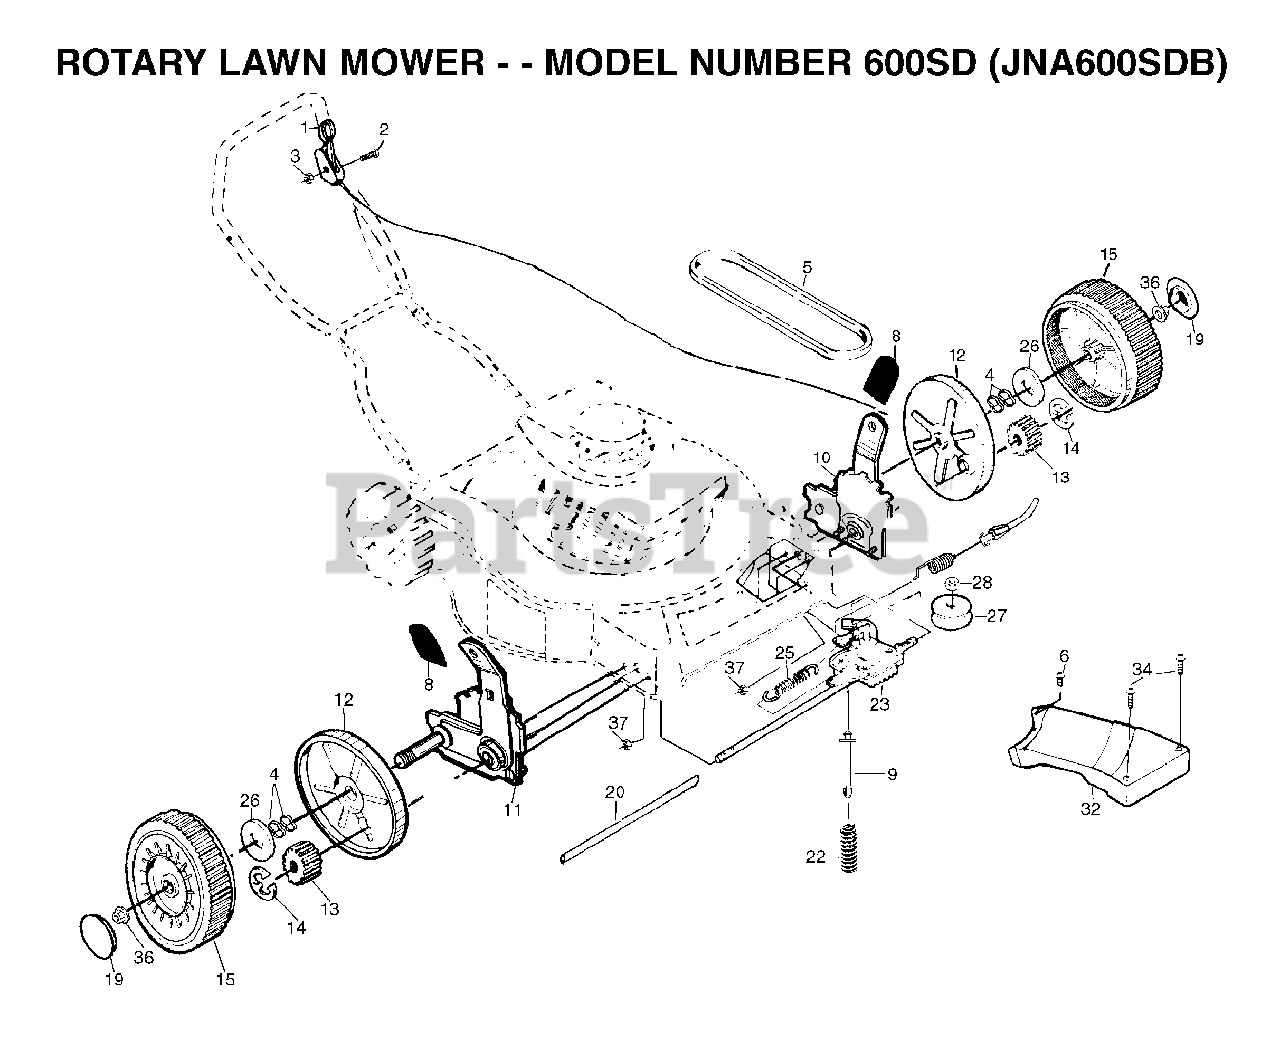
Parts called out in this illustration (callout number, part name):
1	CONTROL
4	WAVE WASHER
5	BELT THERM .32
6	TAPPING SCREW
8	SELECTOR KNOB
9	SPRING RETAINER
12	DUST COVER, WHEEL
13	PINION GEAR
14	E-RING 7/16 RE
15	WHEEL.8X2.RADIAL.GRAY
20	DRV SHAFT TUBE PM
22	SPRING.EXTENSION
23	GEAR CASE ASMBLY
26	WASHER FLUT
27	PULLEY
28	FLANGED LOCKNUT 3/8-16 ZINC
36	HEX FLANGE LOCKNT
37	NUT
